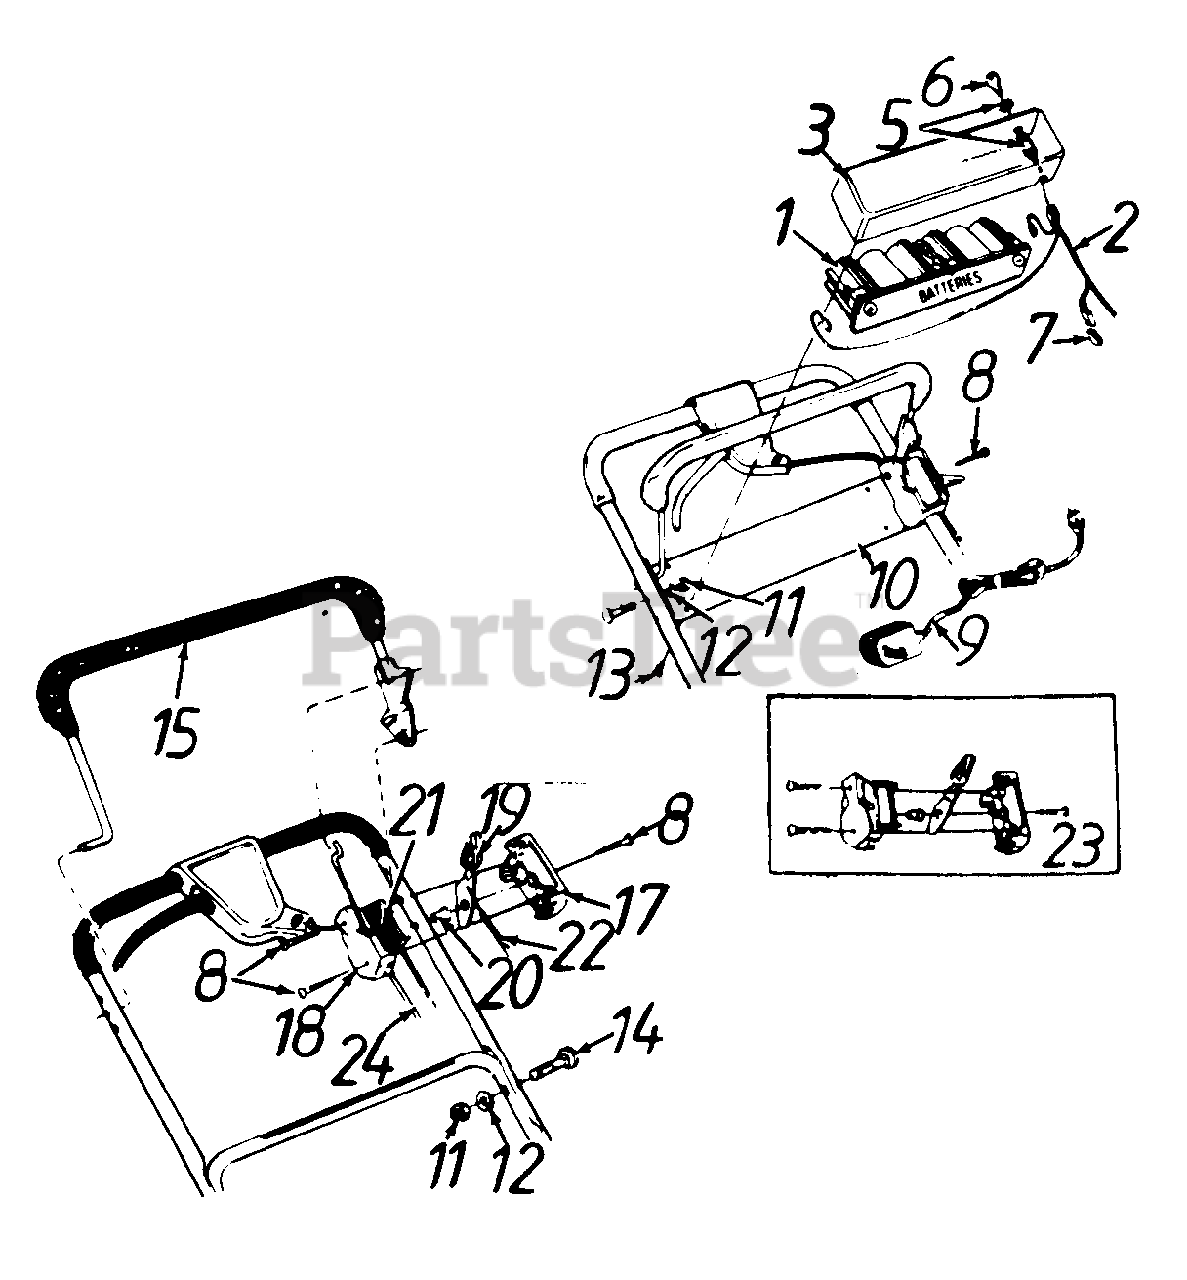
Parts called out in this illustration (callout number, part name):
1	Battery Pack
2	Wire Harness
3	Battery Tray
5	Ignition Switch
6	Ignition Key
7	Plug
8	Truss Mach- Scr. #12 x 1.5"
9	Battery Charger
10	Lower Battery Tray
11	Hex Nut 5/16-18 Thd.
12	L-Wash. 5/16" I.D.
13	Truss Mach. H-Riser Tap Scr. 1" Lg.
14	Curved Carriage Bolt 5/16-18 x 1.38" Lg.
15	Control Handle Ass'y.
17	Control Panel Half
18	Clutch Panel Half
19	Throttle Control Lever
20	Control Disc Pin
21	Control Label-Throttle
22	Throttle Wire-61" Lg.
23	Control Housing Comp.
24	Control Cable-43" Lg.
